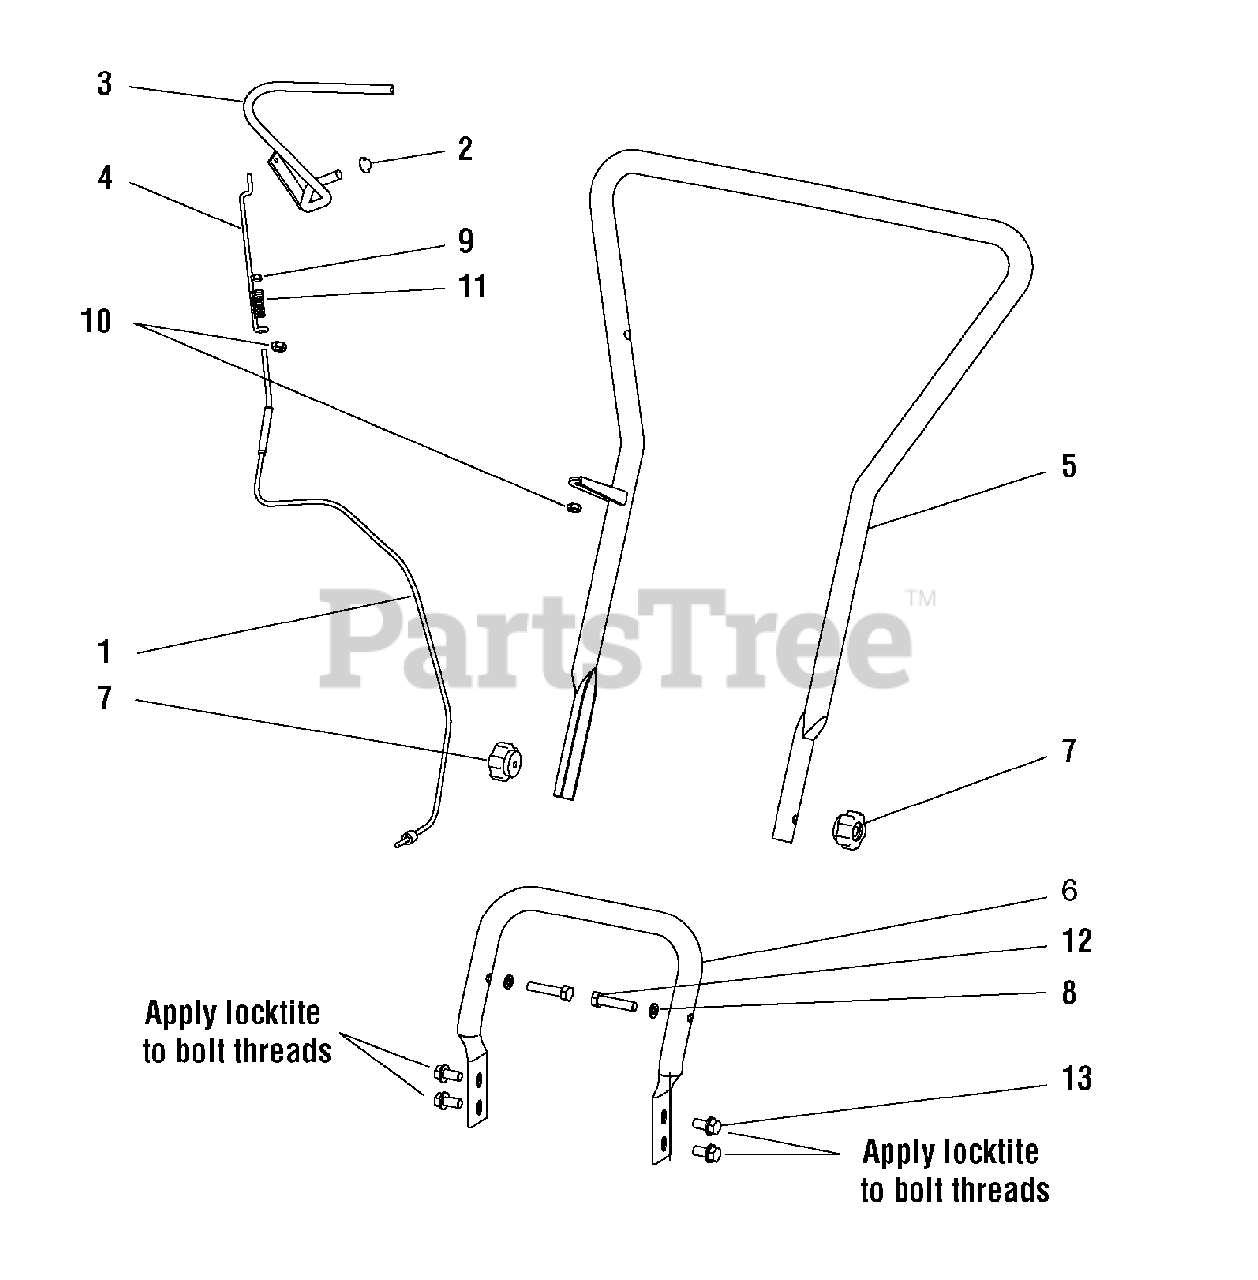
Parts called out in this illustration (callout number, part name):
1	CABLE ASSEMBLY, With Ferrel
2	NUT, Push, 3/8 Dia.
3	LEVER, Drive Safety Control
4	LINK, 5-3/4
5	HANDLE, Top
6	HANDLE. Bottom
7	KNOB, 5-Star, 5/16-18
8	WASHER, Locking, Spring, 5/16
9	NUT, Hex, Nylock, 10-24
10	NUT, Hex-Jam, 5/16-24
11	SPRING, Compression, Forward Arm
12	BOLT, Hex-Head, 5/16-18 x 1-3/4
13	BOLT, Hex-Head, Serated Flange, 3/8-16 x 1
